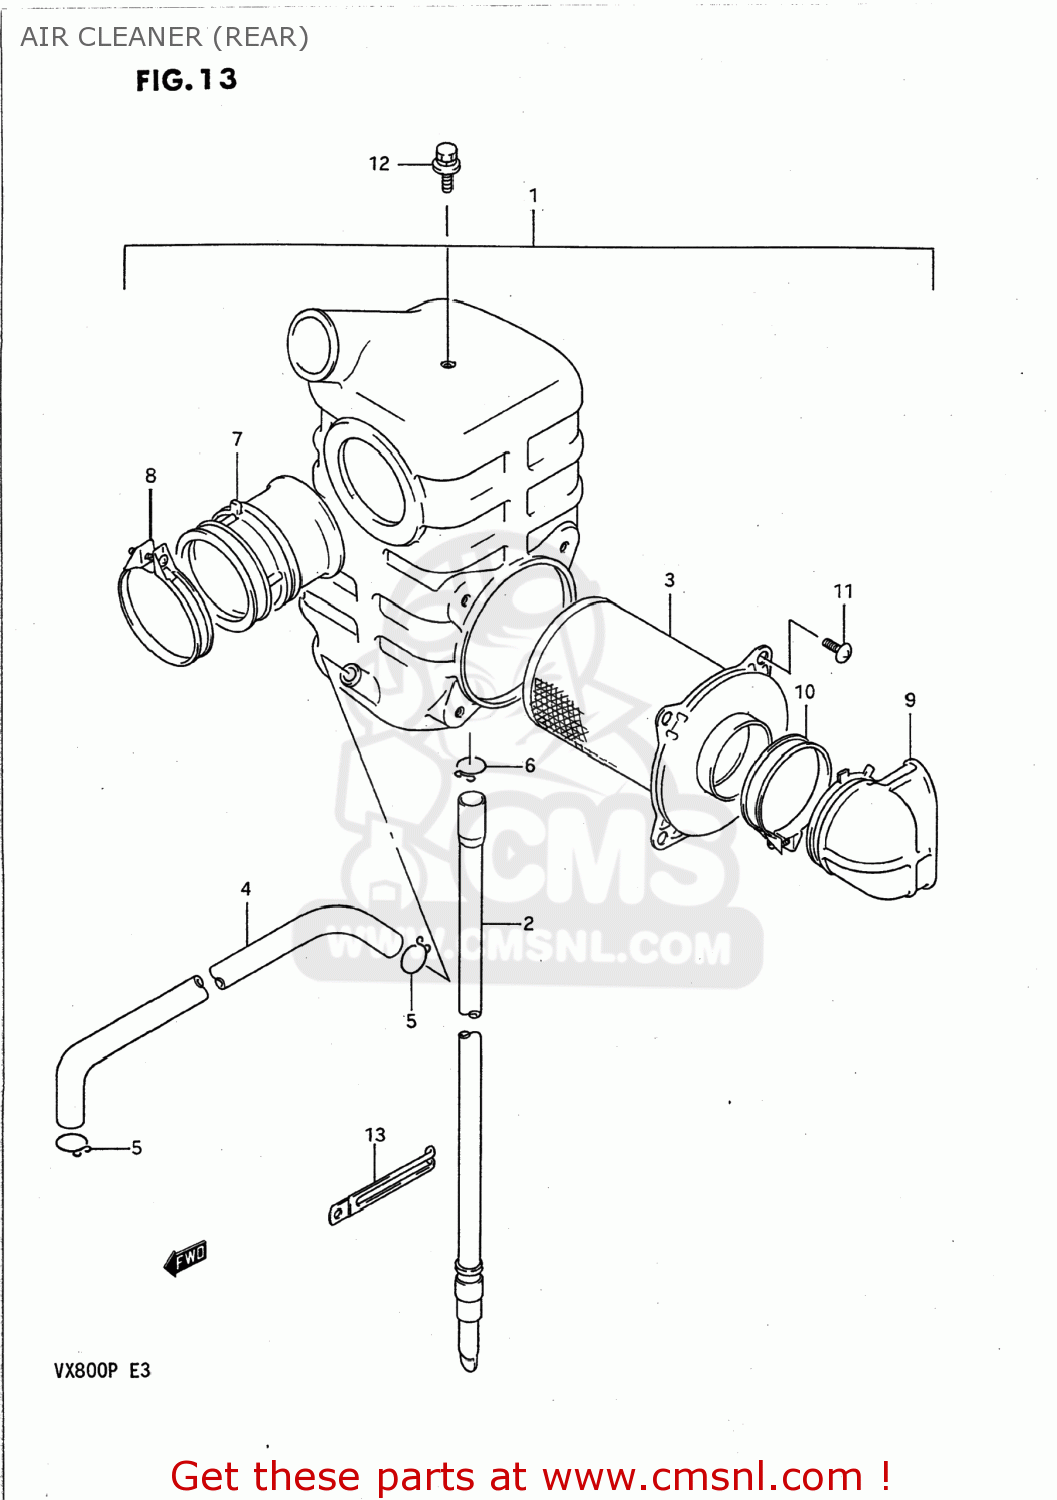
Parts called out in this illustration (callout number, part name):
1	CLEANER ASSEMBLY,AIR,REAR
2	DRAIN TUBE
3	FILTER ASSY,AIR
4	TUBE,BREATHER
5	CLIP
6	CLIP
7	TUBE,OUTLET
8	CLAMP
9	TUBE,INLET
10	CLAMP
11	SCREW
12	BOLT
13	CLAMP
